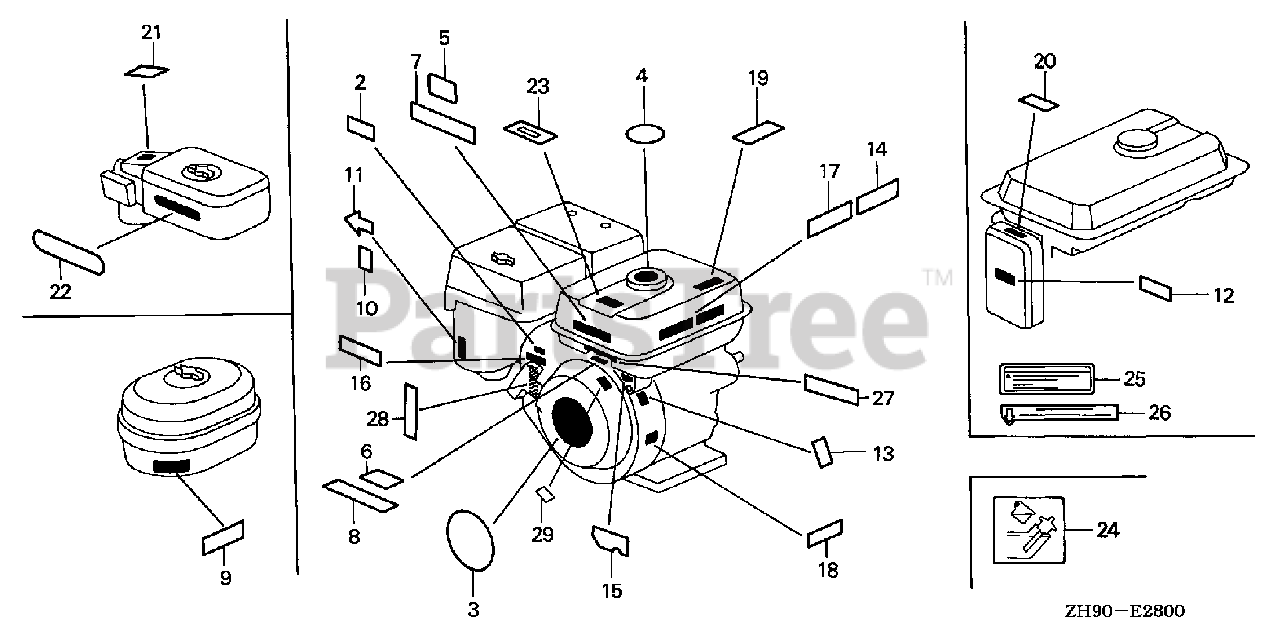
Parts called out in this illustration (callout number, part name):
3	EMBLEM (INTERNAL)
3	EMBLEM
7	LABEL, CAUTION
10	MARK, CHOKE (EXTERNAL)
17	MARK, OIL ALERT (E)
